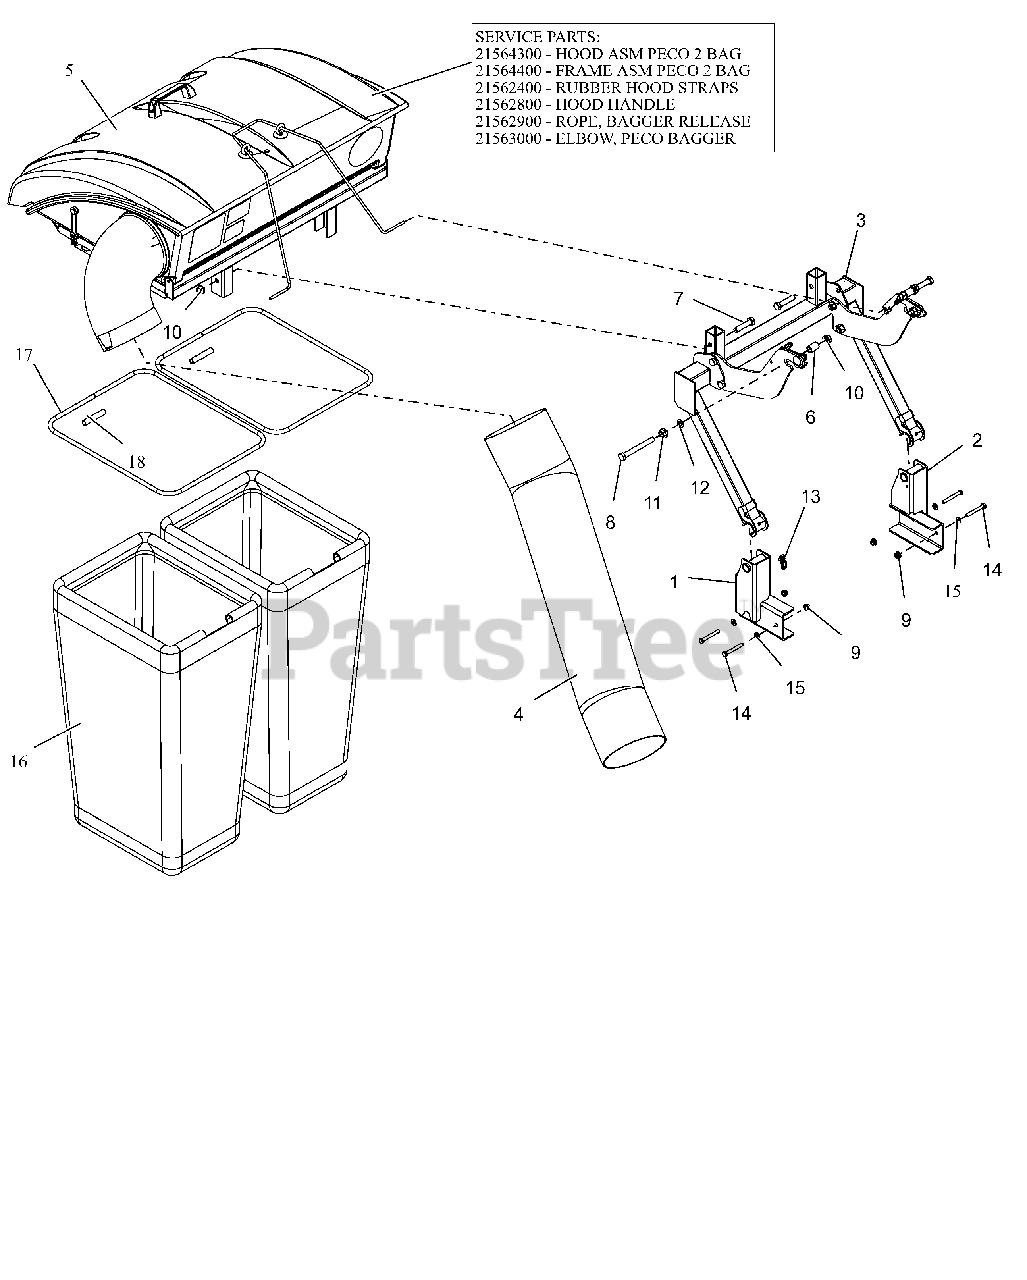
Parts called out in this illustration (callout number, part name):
1	WMT, BAGGER MNT RH PT/PT100
2	WMT, BAGGER MNT LH PT/PT100
3	WMT, BAGGER POST PT/PT100
4	HOSE BAGGER, 49"
5	BAGGER, PECO 2-BAG RECEPTACLE
5	HOOD ASM PECO 2 BAG
5	FRAME ASM PECO 2 BAG
5	RUBBER HOOD STRAP
5	ROPE, BAGGER RELEASE
5	ELBOW, PECO BAGGER
6	SPACER .510 X .75 X 1.1485
7	@BLT-HEX .50-13X2.25 GR5 YWZC
8	@BLT-HEX .5-13-4.5GR8 FULL THD
9	@NUT-LK-NYL-FLG .31-18 YWZC
10	@NUT-LK-TOP-FLG .50-13 YWZC
11	NUT-SPNLK-FLG .50-13 YWZC
12	WSHR-FL-STL .505X.880X.072 YWZ
13	CABLE TIE W/ TREE (.25 HOLE)
14	@BLT-HEX .31-18X2.50 GR5 YWZC
15	@WSHR-FL-STL.344X.688X.065YWZC
16	BAG, DEBRIS COLLECTION
17	FRAME, BAG
18	HOSE, VINYL
